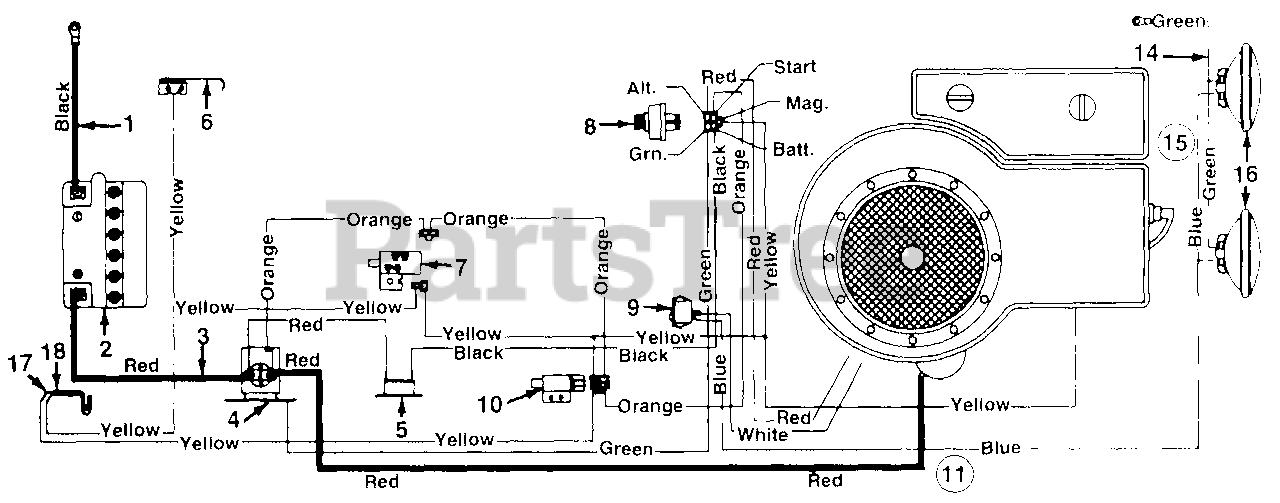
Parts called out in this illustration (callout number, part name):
2	Battery
3	Electric Wire - 8.0" Lg.
4	Solenoid
5	Circuit Breaker
6	Spring Switch (Reverse)
7	Safety Switch (Deck)
8	Ignition Switch
9	Light Switch
10	Safety Switch (Clutch)
15	Headlight Harness
16	Headlight(Round)
17	Safety Switch (Seat)
18	Safety Switch (Seat)
